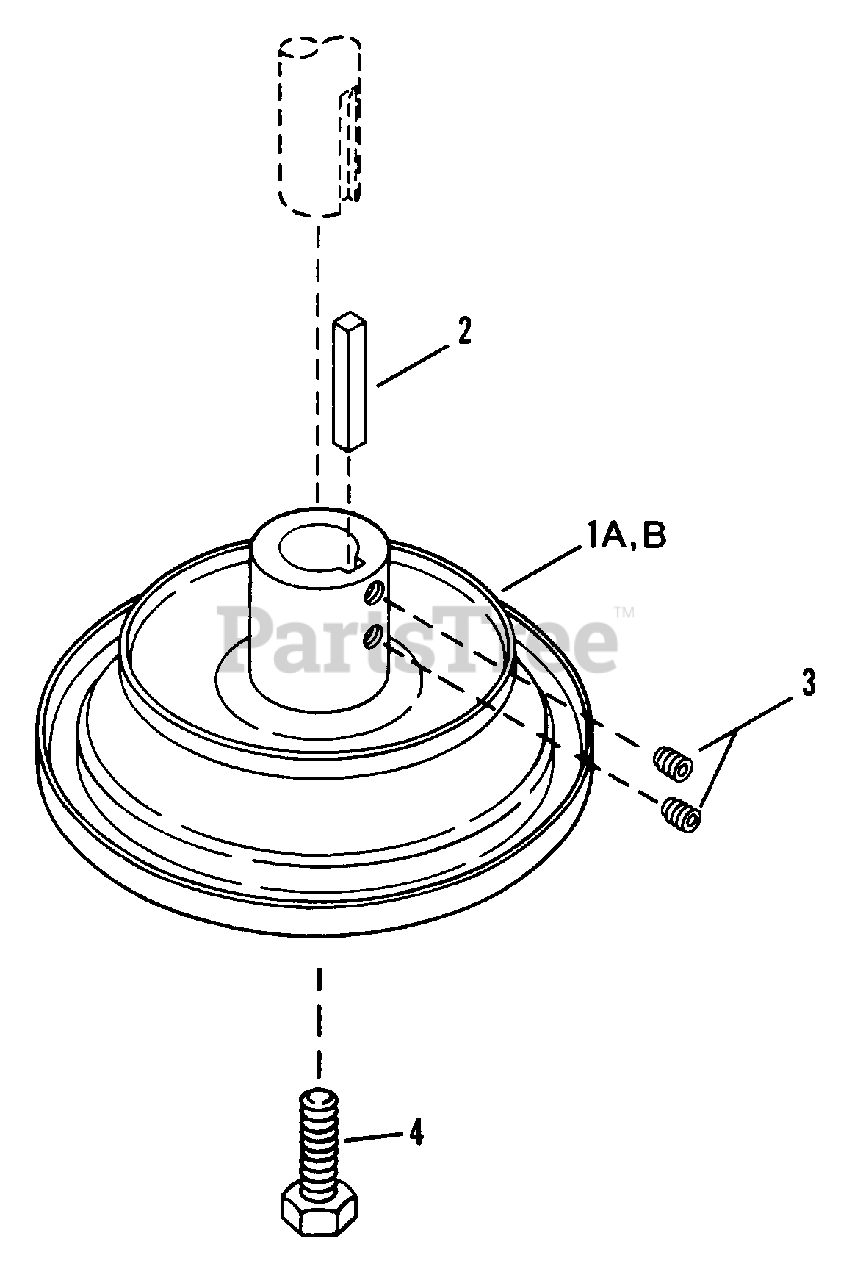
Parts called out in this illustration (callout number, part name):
1A	ASSEMBLY, Drive Disc (A or B)
2	KEY, 1/4 x 1/4 x 2" Square
3	SCREW, 3/8-16 x 3/8" Socket Set
4	SCREW, 7/16-20 x 1" Hex Head Cap
